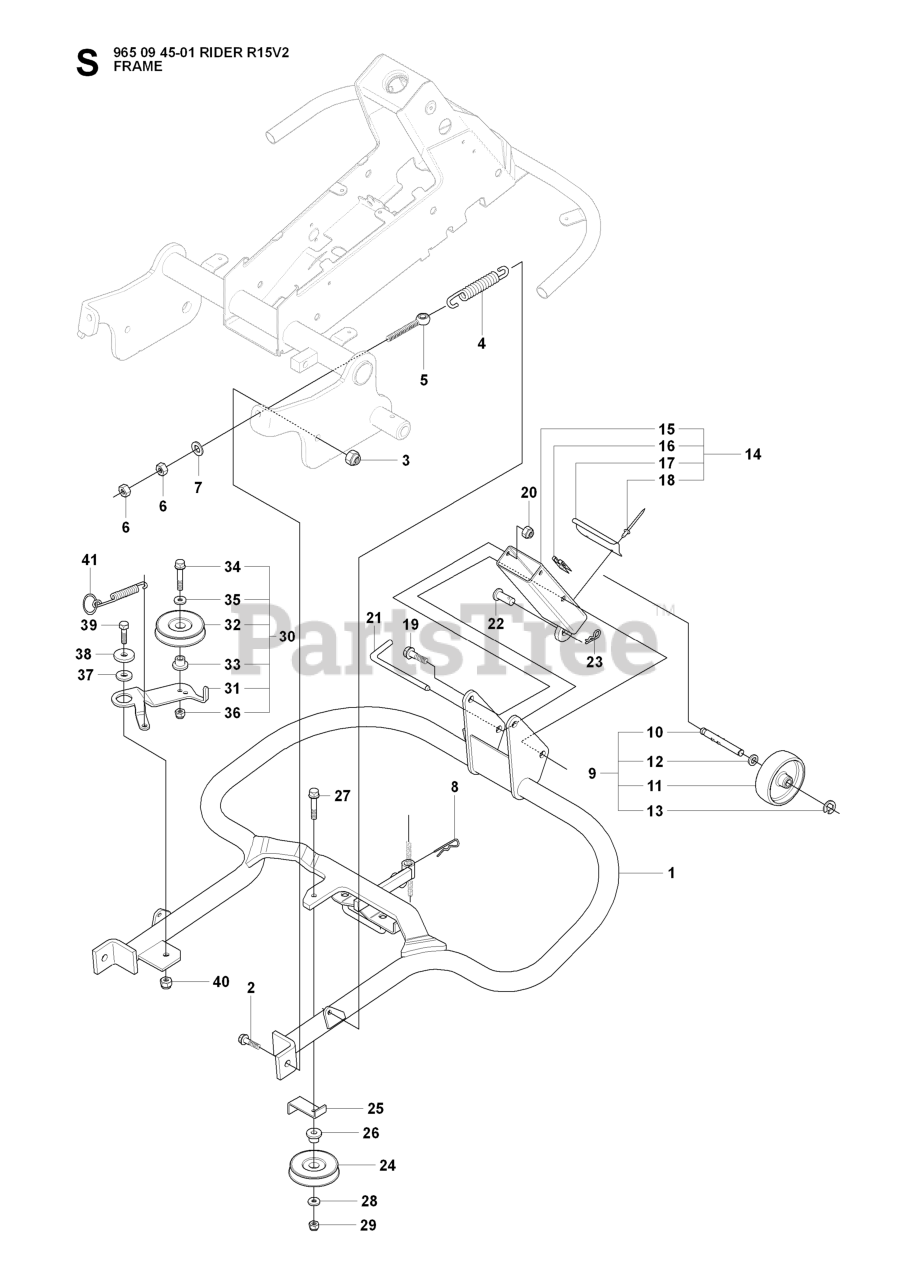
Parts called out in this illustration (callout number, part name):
6	NUT
7	WASHER
9	WHEEL ASSY
13	RETAINING RING
20	LOCKNUT M8
29	LOCKNUT M8
30	BELT TENSIONER ASSY
36	LOCKNUT M8
40	NUT
